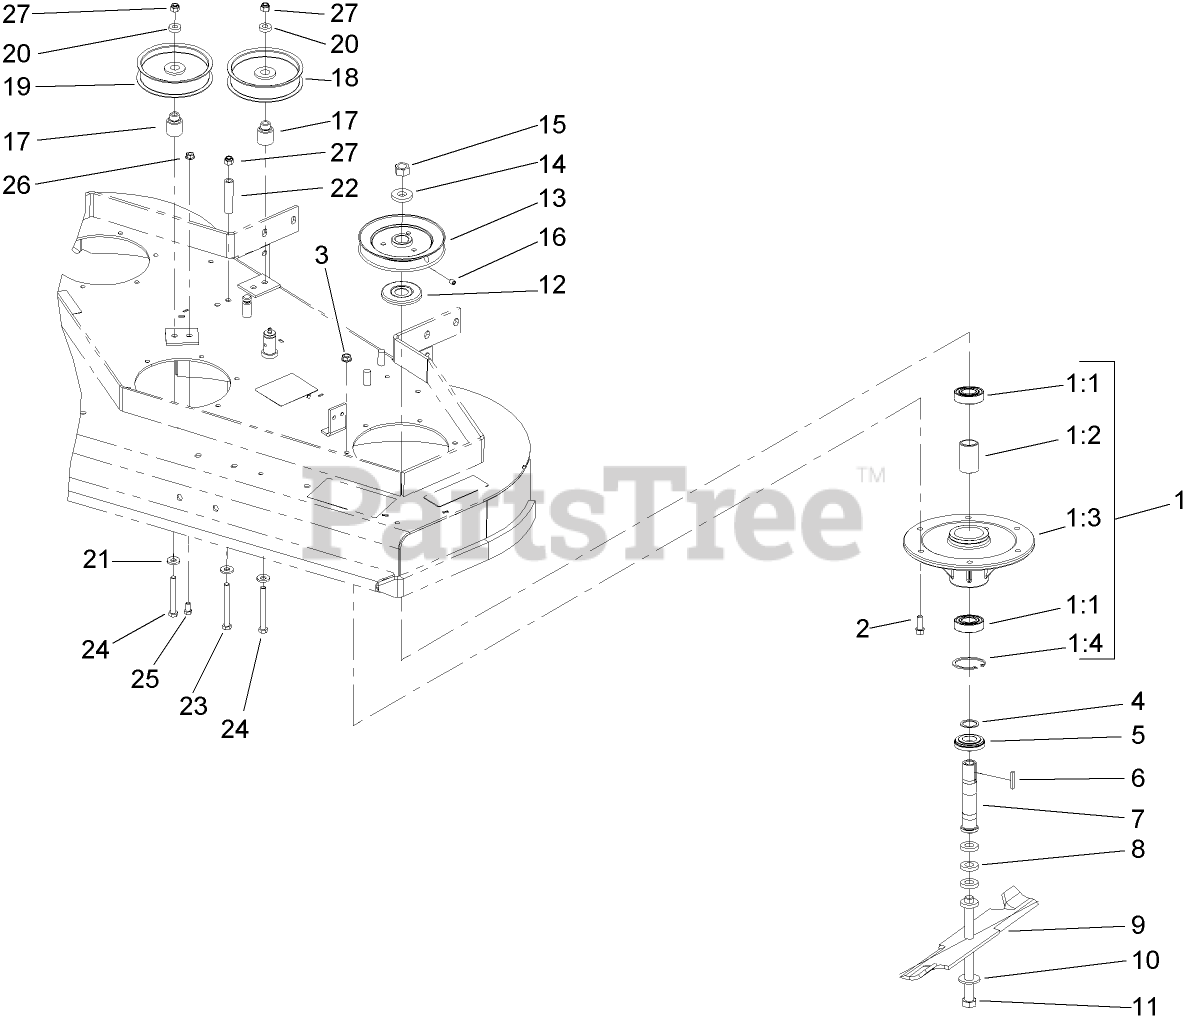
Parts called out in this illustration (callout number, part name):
1	SPINDLE HOUSING ASM
1:1	BEARING
1:2	SPACER-BEARING
1:3	HOUSING-SPINDLE
1:4	RING-SNAP
2	SCREW-HWH
3	NUT-HHF, WHIZ
4	WASHER-SPACER
5	SPACER-GUARD, BOTTOM
7	TUBE-SPINDLE, SHORT
8	SPACER
9	BLADE-Hi FLOW, 18 Inch
10	WASHER-SPRING
11	SCREW-CAP, HH
12	Guard-Bearing, Top
13	SHEAVE
14	WASHER-RETAINER, SHEAVE
15	NUT-HEX
16	SCREW-SET
17	BUSHING-IDLER
18	IDLER-PULLEY, FLAT
19	PULLEY-IDLER
20	SPACER
21	WASHER-BELLEVILLE
22	SPACER
23	SCREW-HH
24	SCREW-HH
25	SCREW-HH
26	NUT-HF
27	NUT-LOCK, NI
